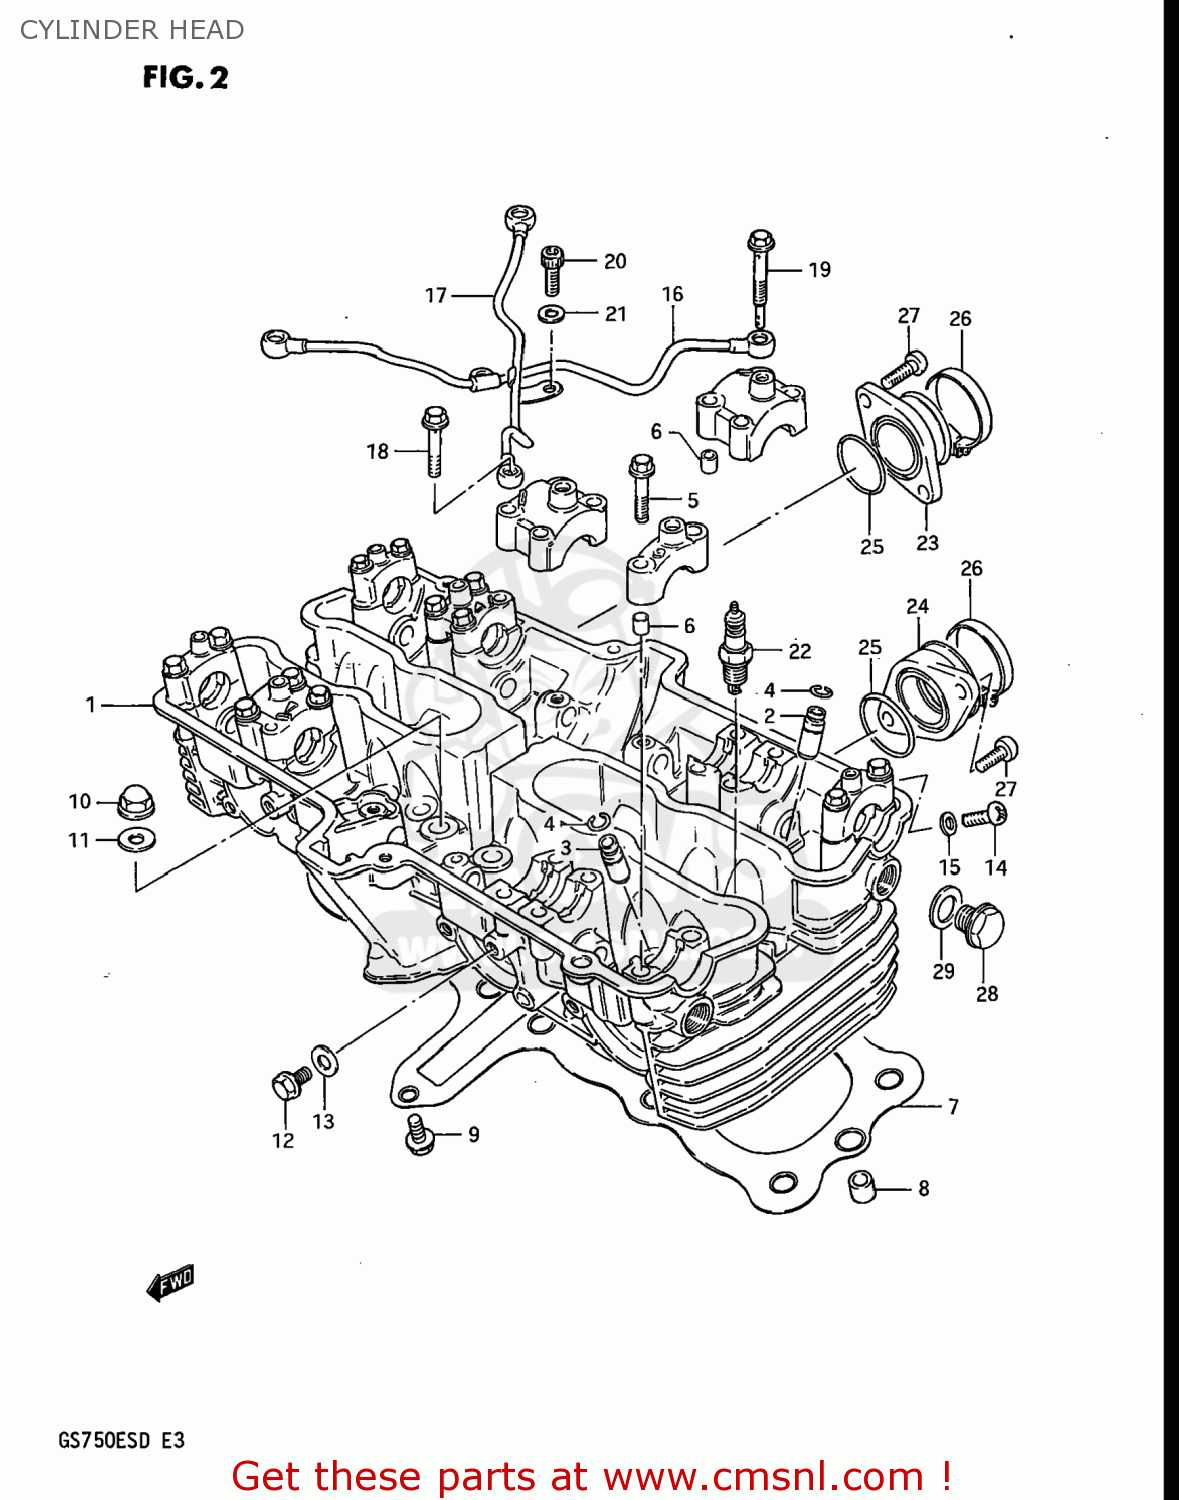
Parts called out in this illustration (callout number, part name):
1	HEAD ASSEMBLY,CYLINDER
2	GUIDE,INTAKE VALVE
3	GUIDE,INTAKE VALVE
4	RING,SNAP
5	BOLT(6X39)
6	PIN(6.2X8X11)
7	GASKET,CYLINDER HEAD (MCA)
8	PIN
9	BOLT
10	NUT
11	GASKET(10.5X22X2) (NAS)
12	BOLT
13	GASKET(6.2X13X1.2) (NAS)
14	SCREW
15	GASKET(5.3X9.3X1.2) (NAS)
16	PIPE,OIL CYLINDER HEAD
17	PIPE,OIL CYLINDER HEAD
18	UNION
19	BOLT,UNION
20	BOLT
21	WASHER
22	SPARK PLUG D8EA
23	PIPE,INTAKE
24	PIPE,INTAKE
25	O-RING
26	CLAMP
27	SCREW
28	PLUG
29	GASKET(14X19.2X2) (NAS)
